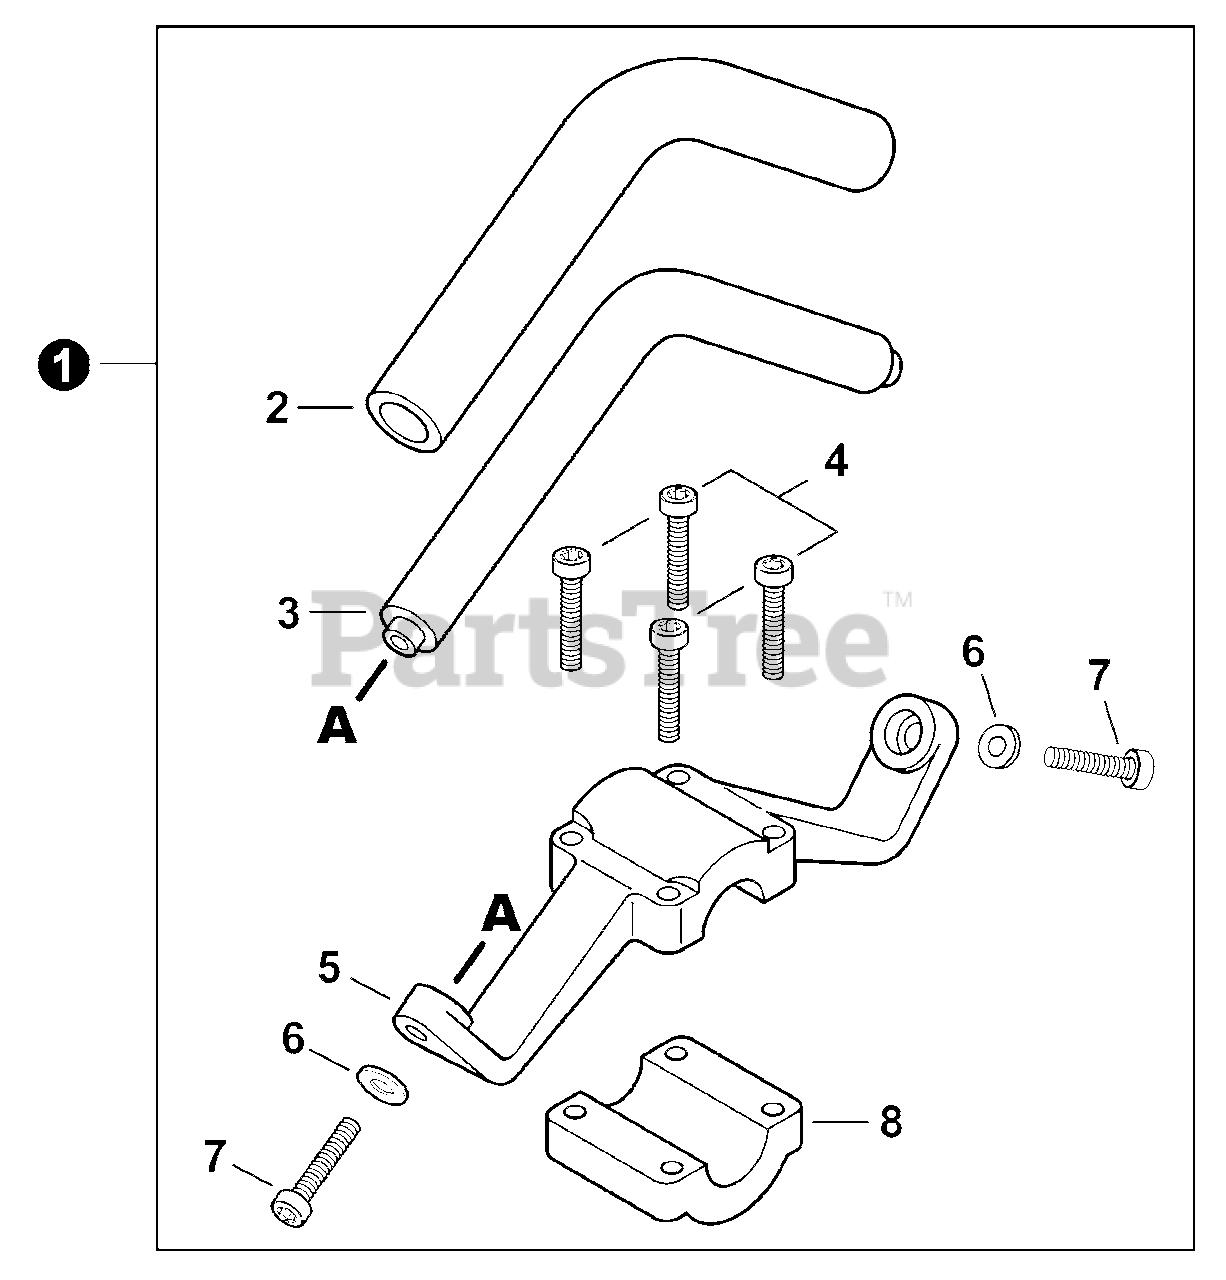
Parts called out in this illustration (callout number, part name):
1	HANDLE ASSY, SUPPORT
2	GRIP, HANDLE
3	HANDLE, SUPPORT
4	BOLT, TORX 5×30
5	BRACKET, HANDLE
6	WASHER, FLAT 5.5×10×0.8
7	BOLT, TORX 5×20
8	BRACKET, HANDLE
